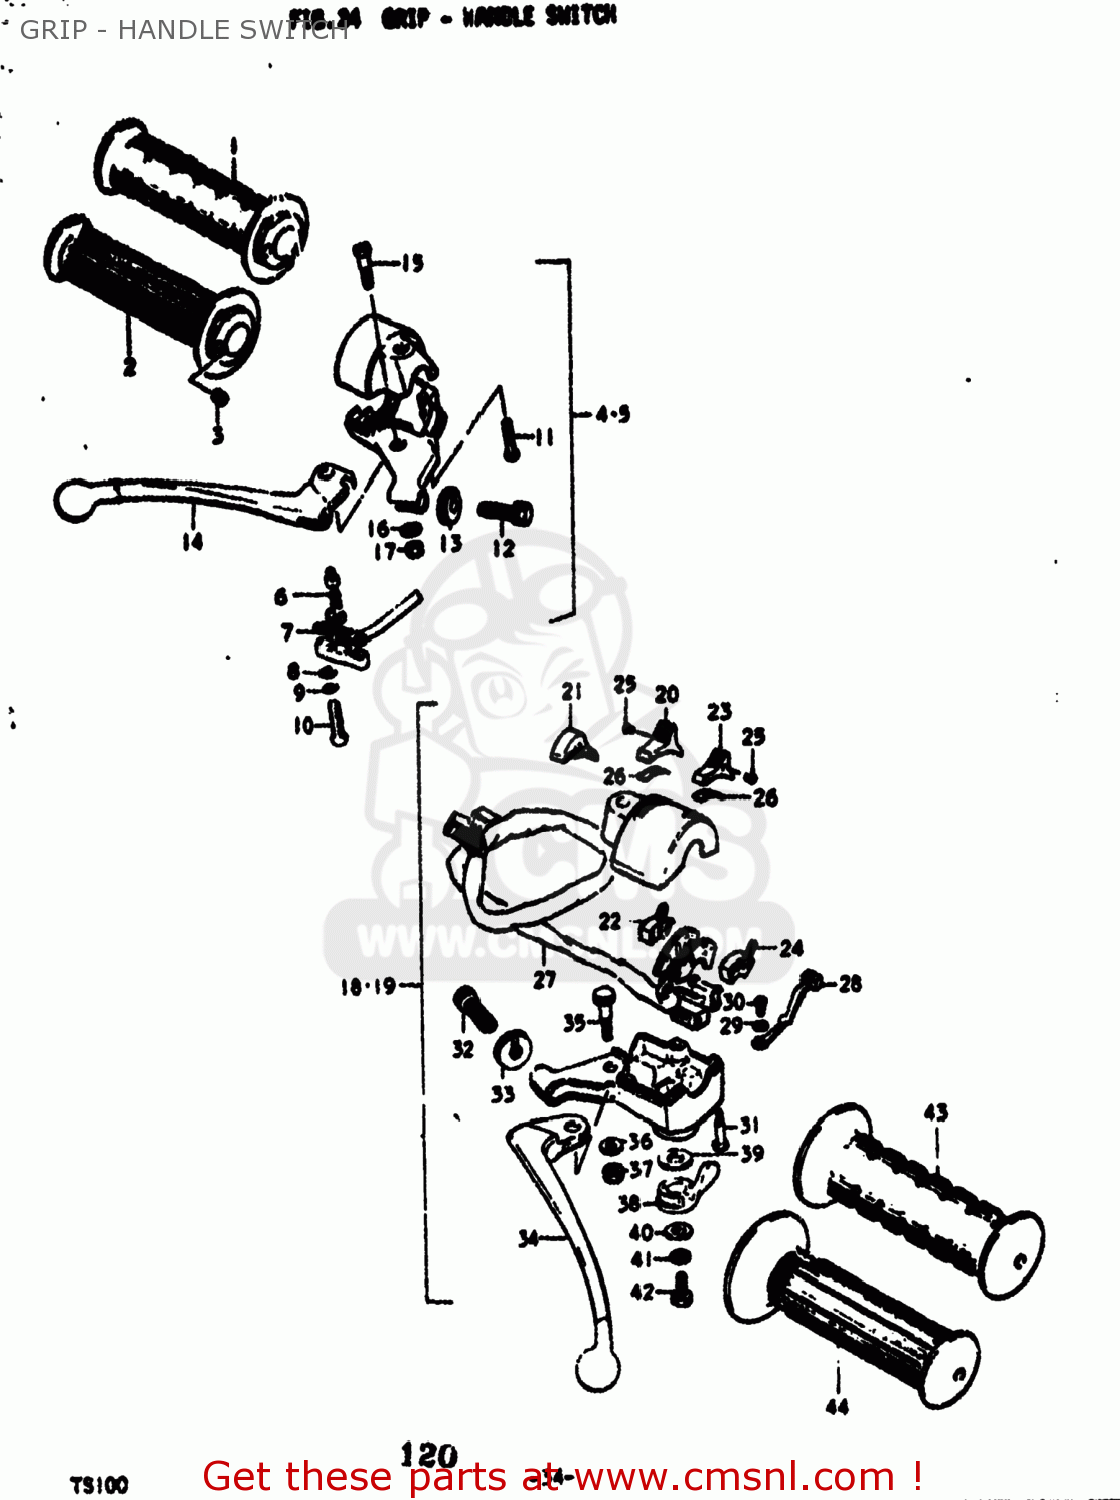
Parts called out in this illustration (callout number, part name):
1	GRIP,THROTTLE
2	GRIP,THROTTLE
3	PIECE,THROTTLE END
4	LEVER/SWITCH ASSEMBLY,BRAKE
5	LEVER/SWITCH ASSEMBLY,BRAKE
6	SPRING
7	SWITCH ASSEMBLY
8	WASHER L,M,A,B
9	LOCK WASHER
10	SCREW
11	SCREW
12	ADJUSTER,CABLE
13	NUT,CABLE ADJUSTER
14	LEVER ASSEMBLY,ADJUST
15	BOLT
16	LOCK WASHER
17	NUT
18	LEVER ASSEMBLY
19	LEVER ASSEMBLY
20	KNOB,HANDLE SWITCH
22	SLIDING BLOCK, LIGHTING
23	KNOB,HANDLE SWITCH
24	SLIDING BLOCK, DIMMER
25	SCREW
26	PLATE,SWITCH KNOB
27	WIRING HARNESS
28	KNOB,TURN SIGNAL SWITCH
30	SCREW
31	SCREW
32	ADJUSTER,CABLE
33	NUT,CABLE ADJUSTER
34	LEVER,CLUTCH
35	BOLT
36	LOCK WASHER
37	NUT
38	LEVER,STARTER
39	WASHER,ADJUSTER
40	WASHER,STARTER LEVER
41	LOCK WASHER
42	BOLT
43	GRIP
44	GRIP,LEFT
